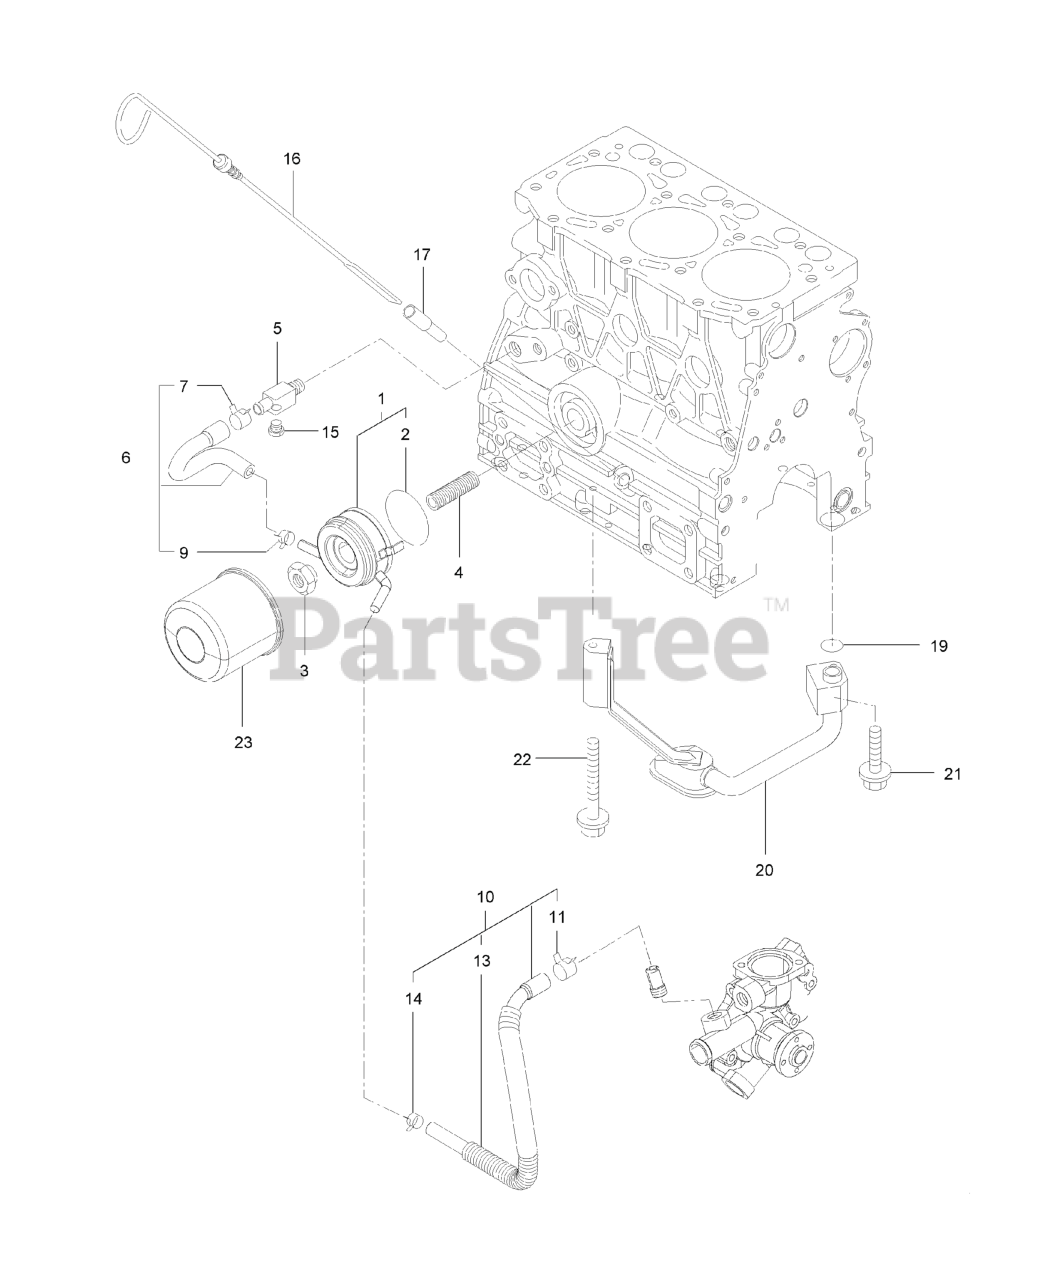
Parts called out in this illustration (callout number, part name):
1	COOLER-OIL
3	NUT-COOLER, OIL
4	STUD-LO FILTER
6	PIPE ASM-COOLER IN
9	CLAMP-HOSE
10	PIPE ASM
14	CLAMP-HOSE
15	PLUG-DRAIN
16	DIPSTICK
17	GUIDE-DIPSTICK
20	PIPE ASM-OIL INLET
23	FILTER ENGINE OIL
